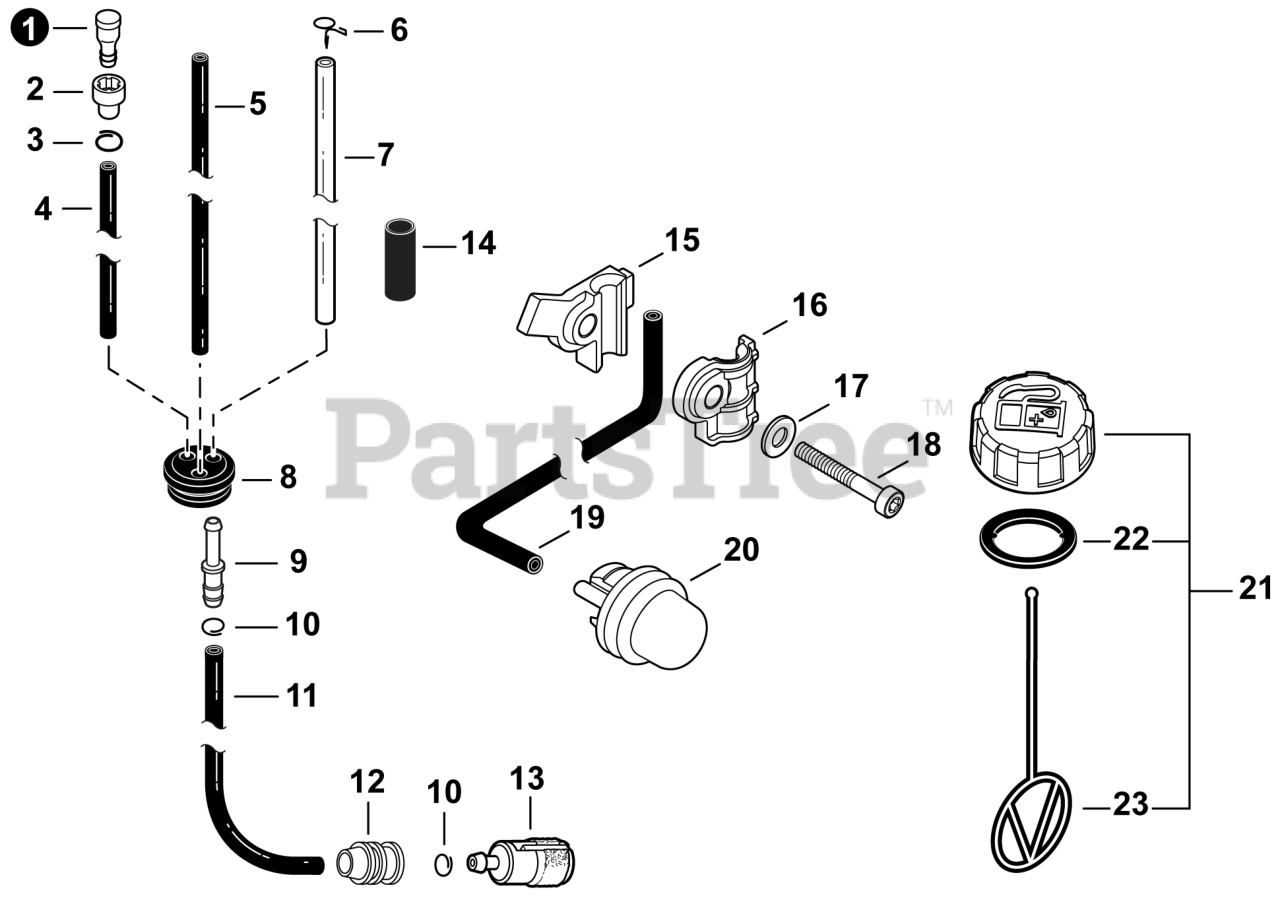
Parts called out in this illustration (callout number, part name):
1	VENT ASSY
2	HOLDER, VENT
3	CLIP 6.5 MM
4	PIPE, FUEL 3x6x130 BLACK
5	PIPE, FUEL 2.4x5x200 BLACK
6	CLIP, SPRING 5.2
7	PIPE, FUEL 3.5x6x210 CLEAR
8	GROMMET, FUEL
9	CONNECTOR, PIPE 5x3.5
11	PIPE, FUEL 3x5x105L BLACK
13	FILTER, FUEL
14	TUBE, FUEL LINE 16x18xL40
15	CLAMP, LOWER
16	CLAMP, UPPER
17	WASHER, FLAT 5.5x10x0.8
18	BOLT, TORX 5x25
19	PIPE, PURGE 2.4x5x140 BLACK
20	BULB, PURGE
21	CAP ASSY, FUEL
22	GASKET, FUEL CAP
23	CONNECTOR, CAP L= 100 MM
